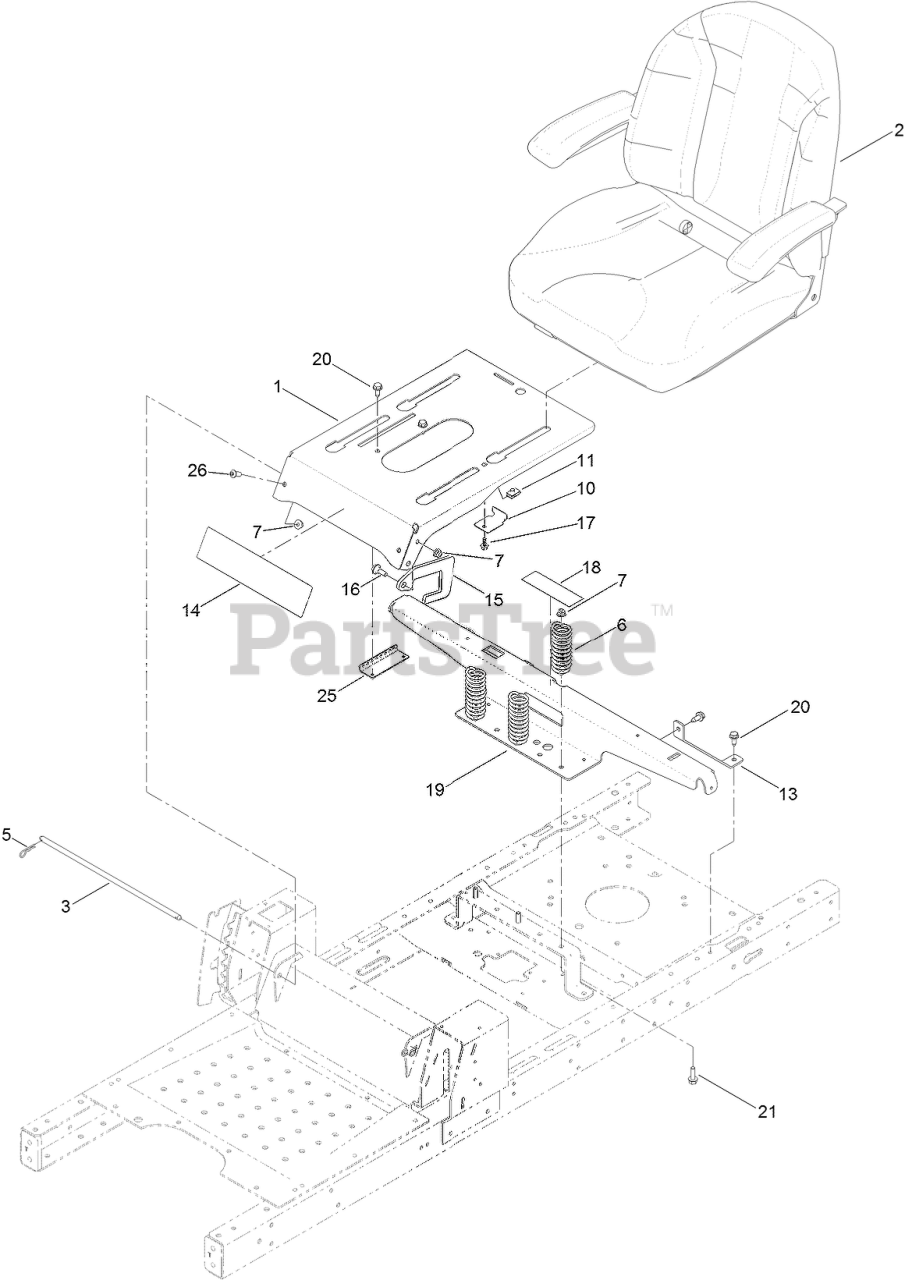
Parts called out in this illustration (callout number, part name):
1	PAN-SEAT
2	SEAT ASM
3	ROD-PIVOT, NARROW
5	PIN-COTTER
6	SPRING-COMPRESSION
7	NUT-HF, NI
10	BRACKET-STOP, SEAT
13	SUPPORT-TANK, REAR
14	DECAL-TIMECUTTER
15	PLATE-STOP
16	SCREW-SHOULDER
17	SCREW-HHF
18	DECAL-SERVICE, CE
19	SUPPORT-POD
20	SCREW-HWHTF
21	SCREW-HHF
25	BRACKET-LATCH, SEAT
26	SCREW-HSBH
